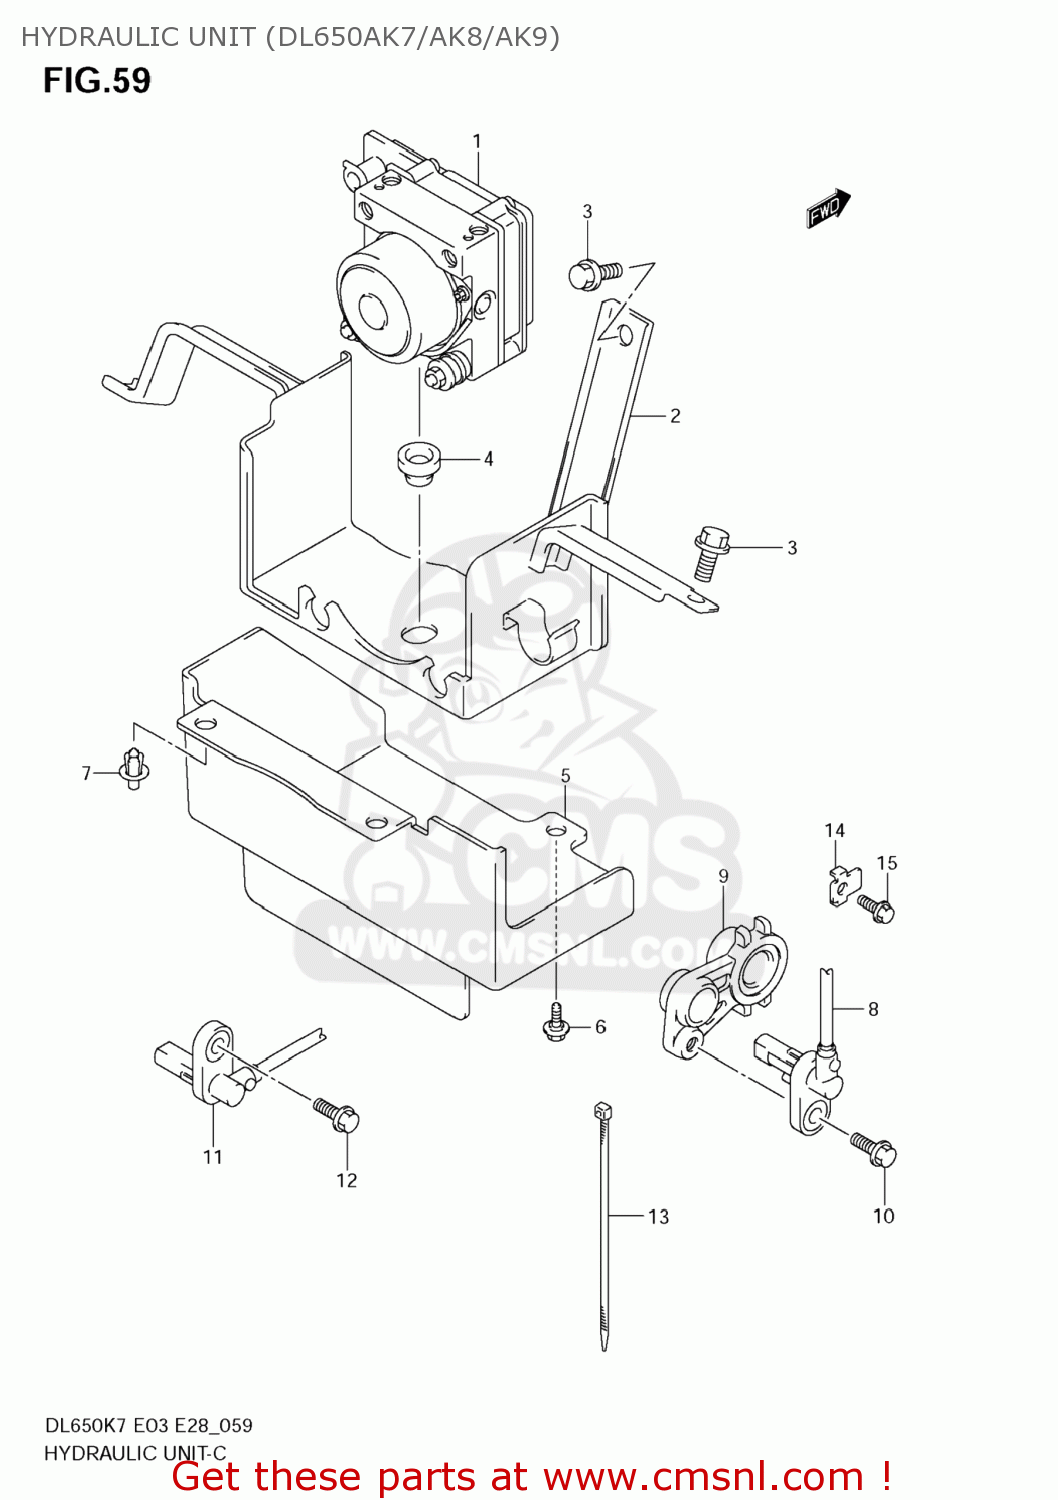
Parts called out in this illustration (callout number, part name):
1	UNIT ASSY,HYDRAULIC ABS
2	HOLDER,HYDRAULIC UNIT ABS
3	BOLT
4	DAMPER,ACTUATOR MOUNT
5	COVER,HYDR ABS UNIT
6	BOLT(6X16)
7	CLIP(BLACK)
8	SENSOR,FR WHEEL ABS
9	BRACKET,SPEED SENSOR FR
10	BOLT
11	SENSOR,RR WHEEL ABS
12	BOLT
13	CLAMP(L:145)
14	GUIDE,SENSOR LEAD
15	BOLT
